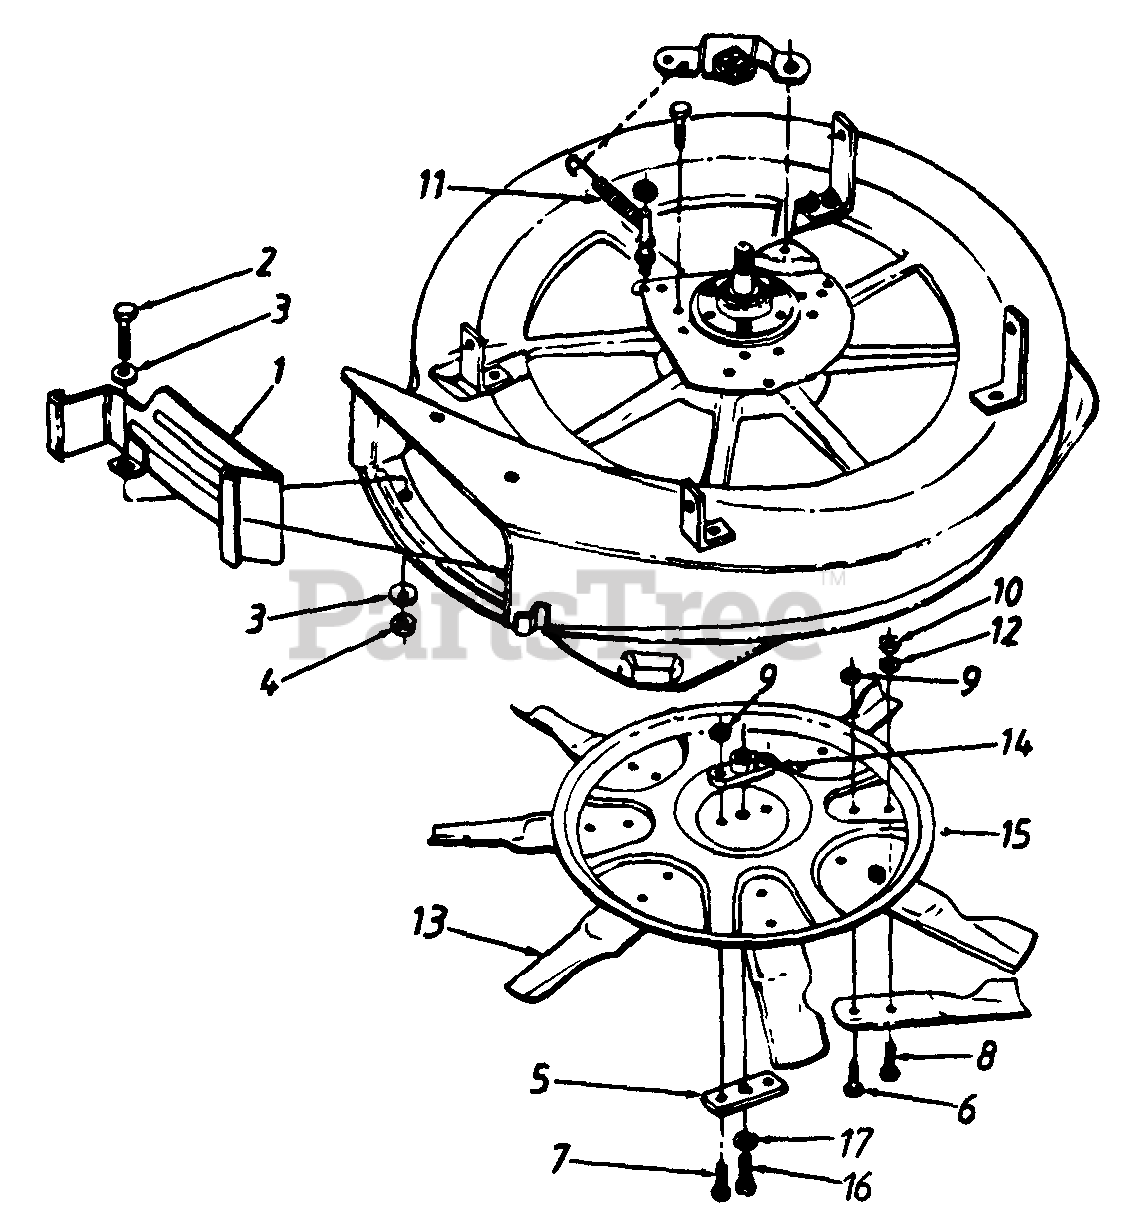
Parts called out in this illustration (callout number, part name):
1	Mulching Baffle Ass'y.
2	Hex Bolt 5/16-18 x .5"
3	Bell-Wash. 325" I.D.
4	Hex L-Nut 5/16-18 Thd.
7	Hex Bolt 5/16-24 x 1.25" Lg. (Gr. 5)
8	Hex Bolt 3/8-24 x .88" Lg.
9	Hex L-Nut 5/16-24 Thd.
10	Hex L-Nut 3/8-24 Thd. (Gr. 5)
11	Extension Spring 3.2" Lg.
12	FI-Wash..406" I.D. x .75"
13	30" Mulching Blade Tip
14	Blade Adapter
15	30" Mulching Blade Disc
16	Hex Bolt 3/8-24 x 1.25" Lg. (Gr. 8)
17	L-Wash. 3/8" I.D
